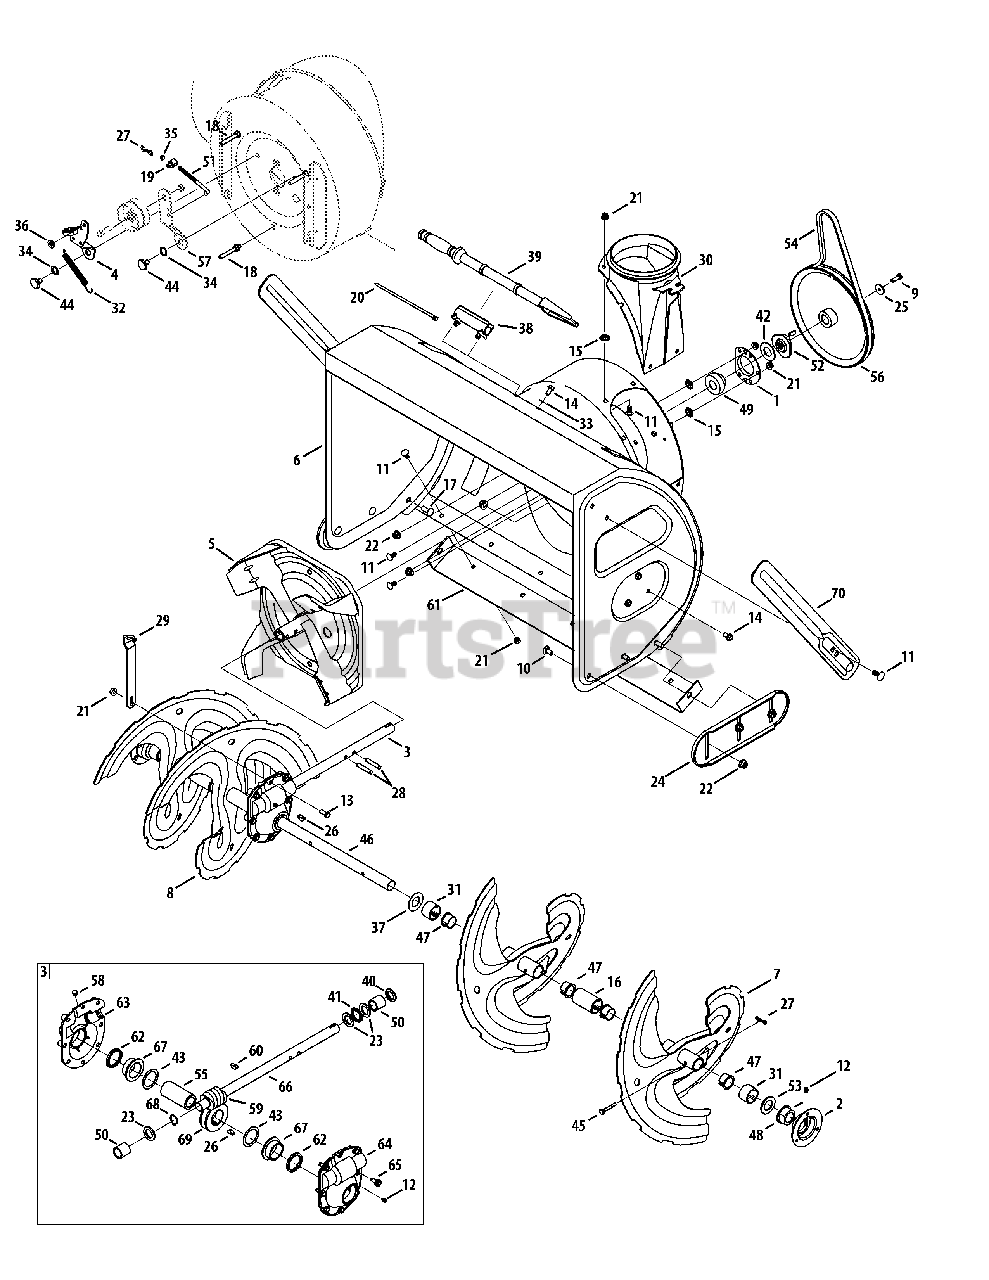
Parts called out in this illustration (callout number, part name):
1	Housing, Bearing
3	Gear Box Assembly
4	Bracket Assembly, Auger Brake
5	Impeller, 16"
6	Housing, Auger
7	Spiral Assembly, LH
8	Spiral Assembly, RH
9	Screw, Hex Cap Lock, 5/16-24
10	Screw, Carriage, 3/8-16 x .75
11	Screw, Carriage, 5/16-18 x .75
12	Fitting, Lube
13	Screw, Hex Cap, 5/16-18 x 1.0 Gr5
14	Screw, 5/16-18 x .750
15	Nut, Push
16	Spacer, 1.0 x 1.5 x 2.5 Lg
17	Screw, Carriage, 3/8-16 x 1.00
18	Screw w/Stud, 5/16-18 x .4300
20	Tie Strap
21	Nut, Hex Flange Lock, 5/16-18
22	Nut, Hex Flange Lock, 3/8-16
23	Wash, Flat, .88 ID x .38 OD
24	Skid Shoe
25	Washer, Flat, .34 x 1.5 x .15 Ht.
26	Key, Woodruff, 1/4 x 3/4
27	Pin, Bow-tie Cotter
28	Pin, Spiral, 5/16 x 1.75
29	Bracket, Gear Box Support
30	Adapter, Chute, 6"
31	Spacer, 1.0 x 1.5 x 1.0 Lg
32	Spring, Extension
33	Washer, Flat, .349 x .879 .063
34	Washer, Wave, .625 x .885 x .015
35	Jam Nut, 5/16-18
36	Washer, .344 x .75 x .12
37	Washer, 1.01 x 1.86 x .06
38	Clip, Mounting
39	Tool, Clean-out
40	Seal, Oil
41	Bearing, Thrust
42	Washer, Flat, .76 x 1.49 x .06
43	Wash, Flat, 1.52ID x 2.0 OD
44	Screw, Shoulder, .625 x .17
45	Pin, Shear, .25 x 1.75
46	Shaft, Spiral
47	Bushing, Flange,
48	Bearing, Flange w/Flats
49	Bearing, Self Aligning
51	Rod, Auger Idler
52	Adapter, Pulley w/Pins
53	Spacer, 1.004 x 1.375 x .25
54	V-Belt, 1/2 x 42
55	Shaft, Gear, Worm
56	Pulley, Auger Drive, 10.0
57	Bracket, Auger Idler
59	Gear, Worm
60	Key, Hi Pro, 3/16 x 3/4
63	Hsg, Ass’y, Auger RH (Incl. Ref. 62 & 67)
64	Hsg, Ass’y, Auger LH (Incl. Ref. 62 & 67)
65	Screw, LD, 5/16-18 x .750
66	Shaft, Drive, Auger
67	Flange Bearing
68	External, Retaining, Ring
69	Gear, Worm, LH
